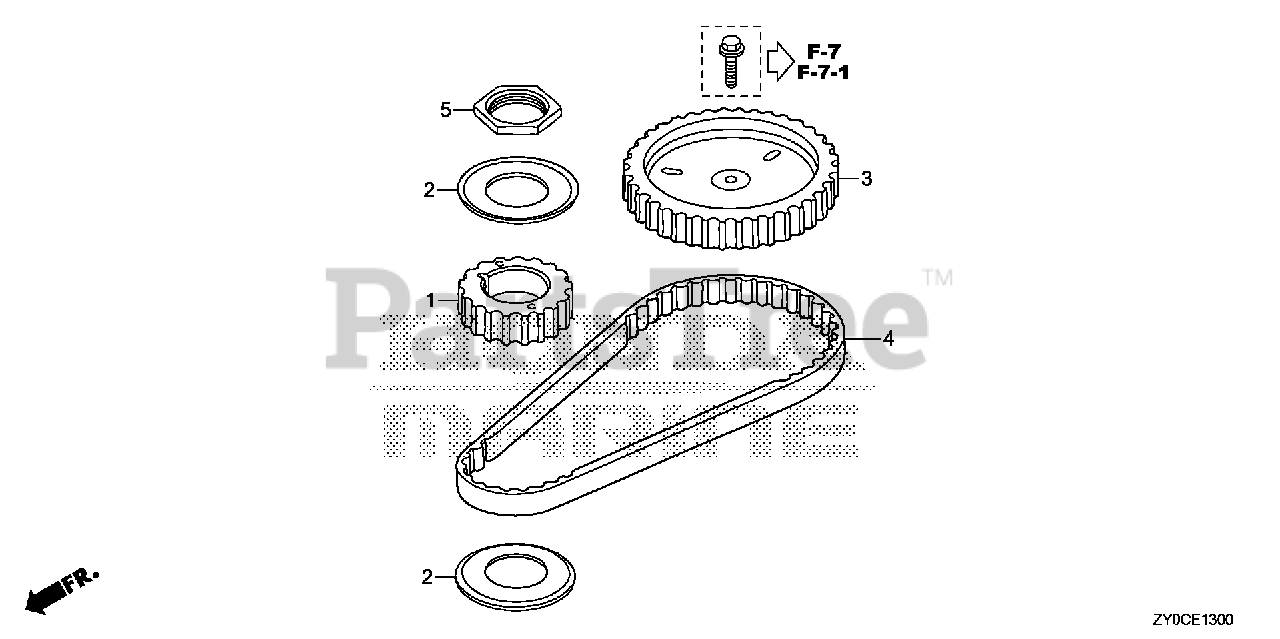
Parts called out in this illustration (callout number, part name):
1	PULLEY, TIMING
2	FLANGE, TIMING PULLEY
3	PULLEY, CAMSHAFT
4	BELT, TIMING (71RU13 B-333)
5	NUT, LOCK (30MM)
